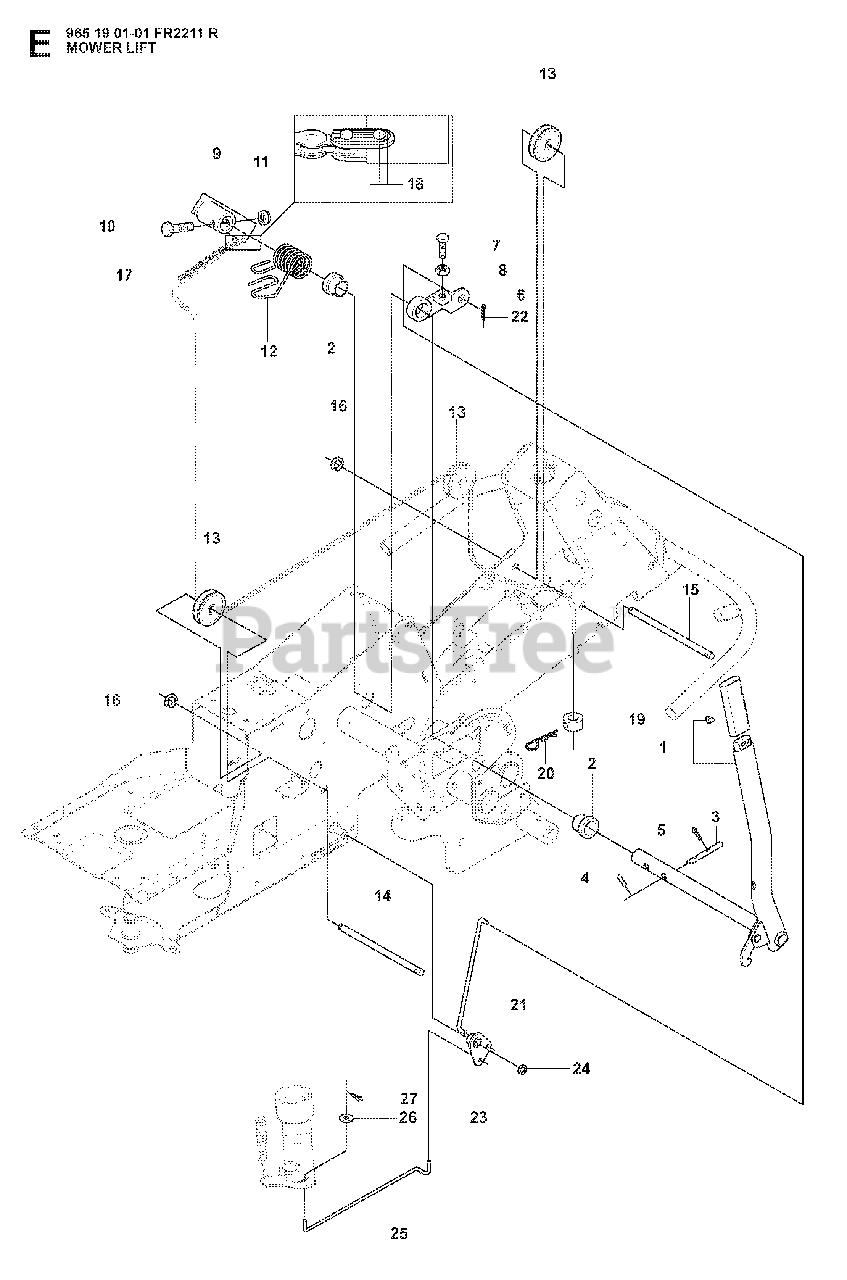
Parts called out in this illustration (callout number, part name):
1	LIFTING LEVER ASSY
2	BUSH
3	RP PIN
5	SPLIT PIN
6	LEVER CLUTCH
9	LIFTING ARM
16	LOCK RING
21	CONNECTION ROD
22	SPLIT PIN
24	RETAINING RING
25	CONNECTION ROD
27	SPLIT PIN
